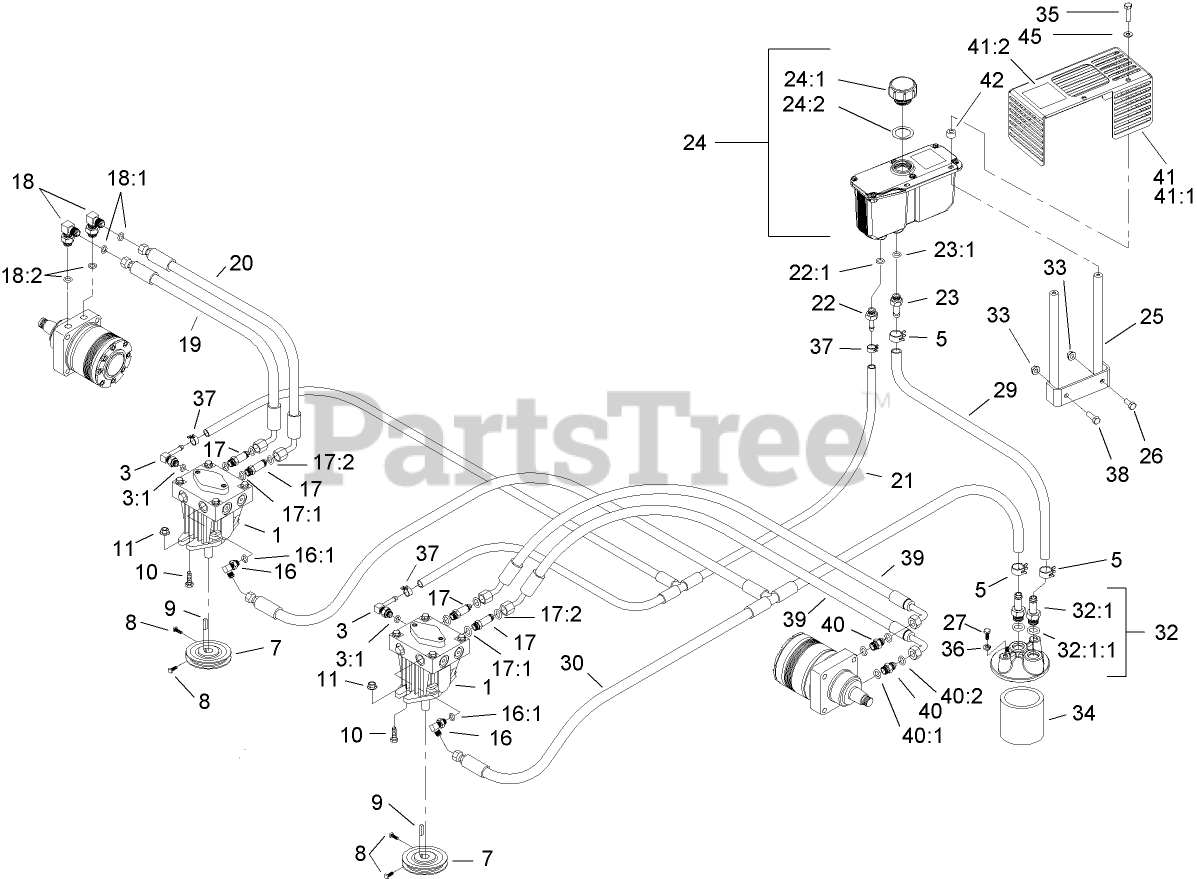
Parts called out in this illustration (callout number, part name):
1	PUMP-HYD
3	ELBOW-90 DEG
3:1	O-RING
5	Clamp-Hose
7	PULLEY
8	SCREW-SET
10	SCREW-HH
11	NUT-HHF, WHIZ
16	FITTING-ELBOW, 90 DEG
16:1	O-RING
17	ADAPTER-HYD, STRAIGHT
17:1	O-RING
17:2	O-Ring
18	FITTING-HYD, 90 DEG
18:1	O-Ring
18:2	O-RING
19	HOSE-FRONT
20	HOSE-REAR
21	HYD HOSE ASM
22	Adapter-Straight
22:1	O-RING
23	ADAPTER-STRAIGHT
23:1	O-RING
24	Reservoir-HYD
24:1	CAP-RESERVOIR, HYD
24:2	GASKET-CAP
25	STAND-RESERVOIR
26	SCREW-HH
27	SCREW-HH
29	HYD HOSE ASM
30	HYD HOSE ASM
32	Filter Head ASM
32:1	ADAPTER-STRAIGHT
32:1:1	O-RING
33	NUT-HF
34	FILTER-OIL, HYD
34	FILTER-OIL, HYD (WINTER)
35	SCREW-HH
36	WASHER-LOCK
37	Clamp-Hose
38	SCREW-HH
39	HOSE ASM
40	Fitting-Straight
40:1	O-RING
40:2	O-Ring
41	SHIELD ASM
41:1	SHIELD-HEAT, HYD RESERVOIR
41:2	DECAL-SURFACE, HOT (CE)
42	Spacer
45	WASHER-FLAT
